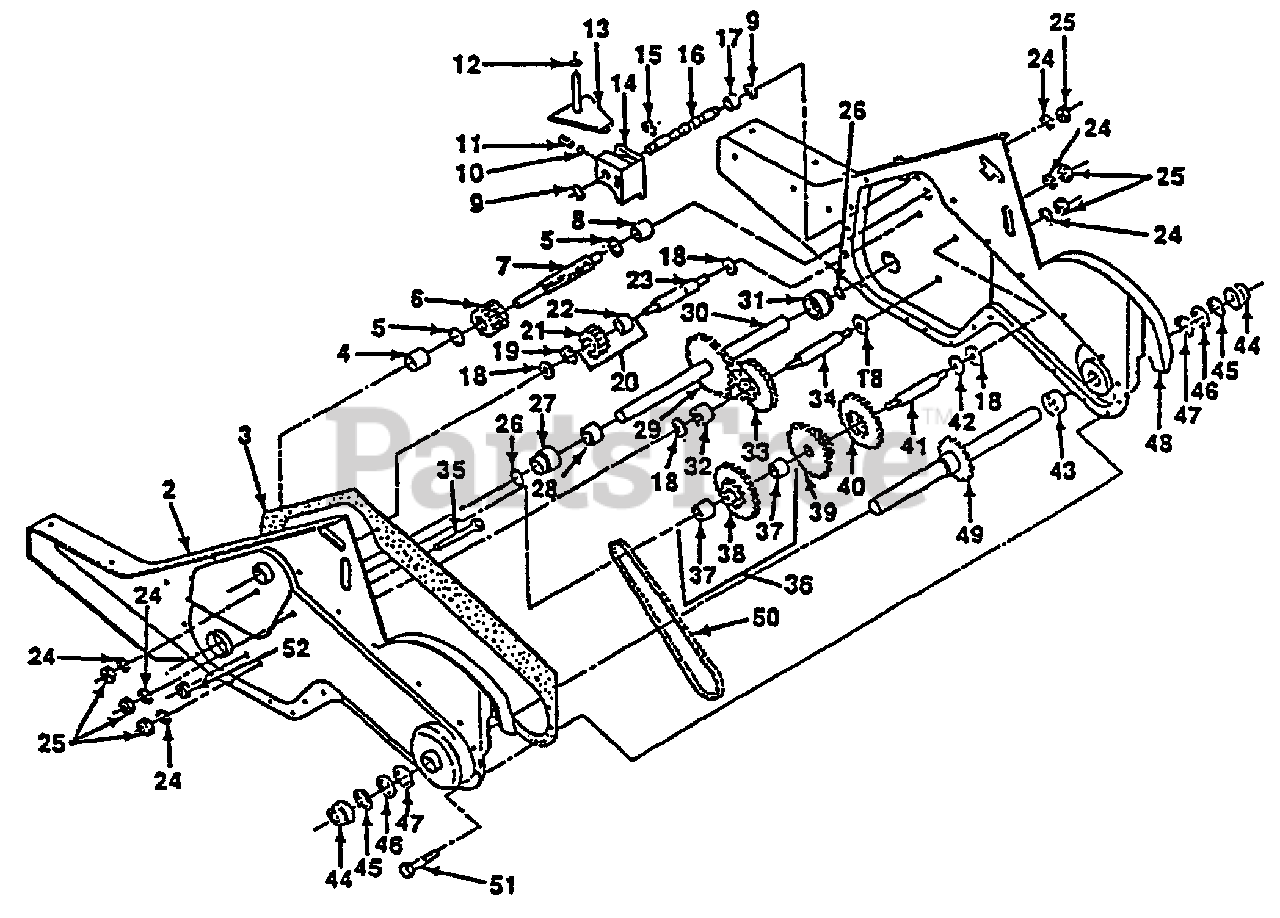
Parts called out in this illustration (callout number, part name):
2	Gearcase, LH. w/Bearing
3	Gearcase
4	Bearing, Needle
5	Washer, Thrust 5/8 x 1.10 x 1/32
6	Pinion, Input
7	Shaft, Input
8	Bearing, Needle
9	Washer, Seat
10	Ball, Steel
11	Spring, Shift, Fork
13	Arm, Shift
14	Fork, Shift
15	Ring, Klip
16	Shaft, Shift
17	Spacer, Split
19	Ring, Klip
20	Gear, Assembly, Reverse Idler
21	Gear, Reverse Idler
22	Bearing, Needle
23	Shaft, Reverse Idler
24	Washer, Lock 7/16
25	Nut, Hex 7/16-20
27	Bearing, Shaft, Ground Drive
28	Spacer 0.765 x 1.125 x 1.23
29	Chain #35-50 Pitch
30	Ground Shaft Assembly
31	Bearing, Shaft, Ground Drive
32	Spacer 0.70 x 1.00 x 1.150
33	Sprocket and Gear Assembly
34	Shaft, Reduction (2nd)
35	Screw, Whiz, Lock 5/16-18 x 3-1/2
36	Sprocket Assembly w/Bearing
37	Bearing, Needle
38	Sprocket, Tine
39	Gear, Cluster, Red 1st & 2nd
40	Gear, Reverse
41	Shaft, Reduction (1st)
42	Washer, Thrust
43	Spacer 1.01 x 1.75 x 0.760
44	Cup, Formed
45	Ring, Spiral
46	Seal, Ring, Rubber
47	Seal, Oil
48	Gearcase, R.H. w/Bearing
49	Shaft, Tine
50	Chain, Roller #50-50 Pitch
51	Screw 1/4-20 x 1/2
52	Nut, Hex 5/16-18
